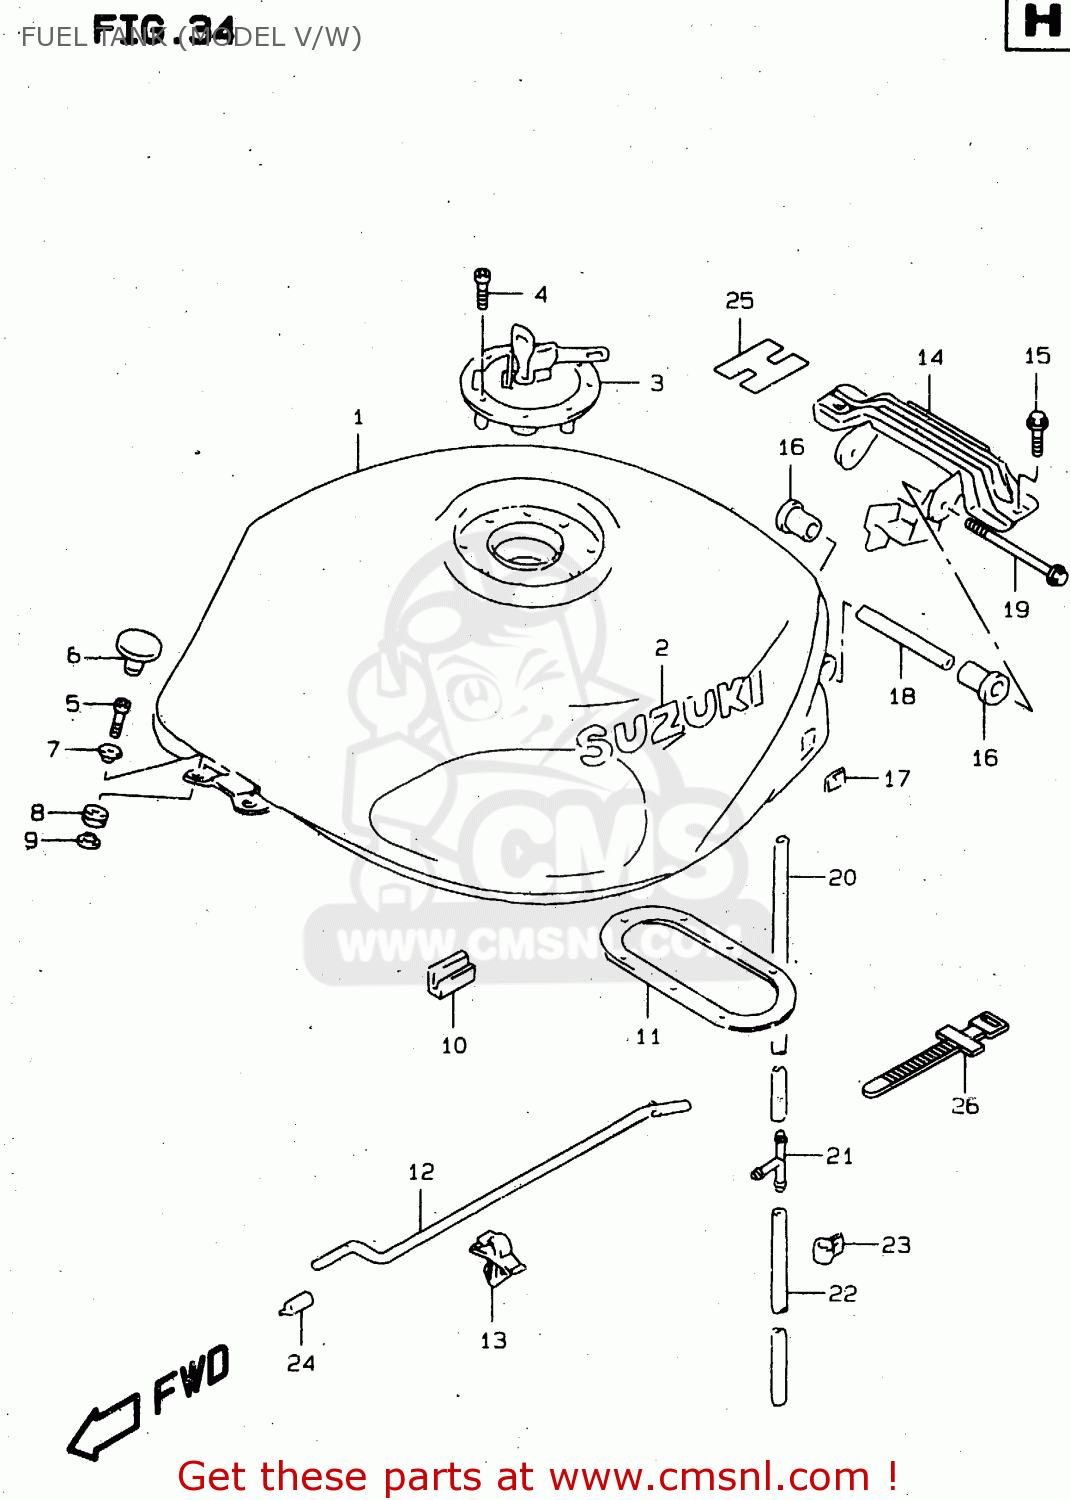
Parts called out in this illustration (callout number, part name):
1	TANK ASSEMBLY,FUEL
2	EMBLEM,FUEL TANK
3	CAP SET,FUEL TANK
4	BOLT(5X20)
5	BOLT
6	CAP,BOLT
7	WASHER(6.5X18X1.6)
8	CUSHION
9	WASHER
10	CUSHION,FUEL TANK SIDE
11	PACKING,FUEL PUMP
12	STAY,FUEL TANK
13	CLAMP
14	BRACKET,FUEL TANK,REAR
15	BOLT
16	CUSHION,FUEL TANK RR
17	FASTENER,FUEL TANK
18	SPACER,FUEL TANK RR
19	BOLT
20	HOSE(7X10.2X600)
21	3 WAY
22	HOSE(7X10.2X600)
23	CLAMP
24	CAP,OD:11
25	LABEL,FUEL TANK INNER
26	CLAMP(L:125)
